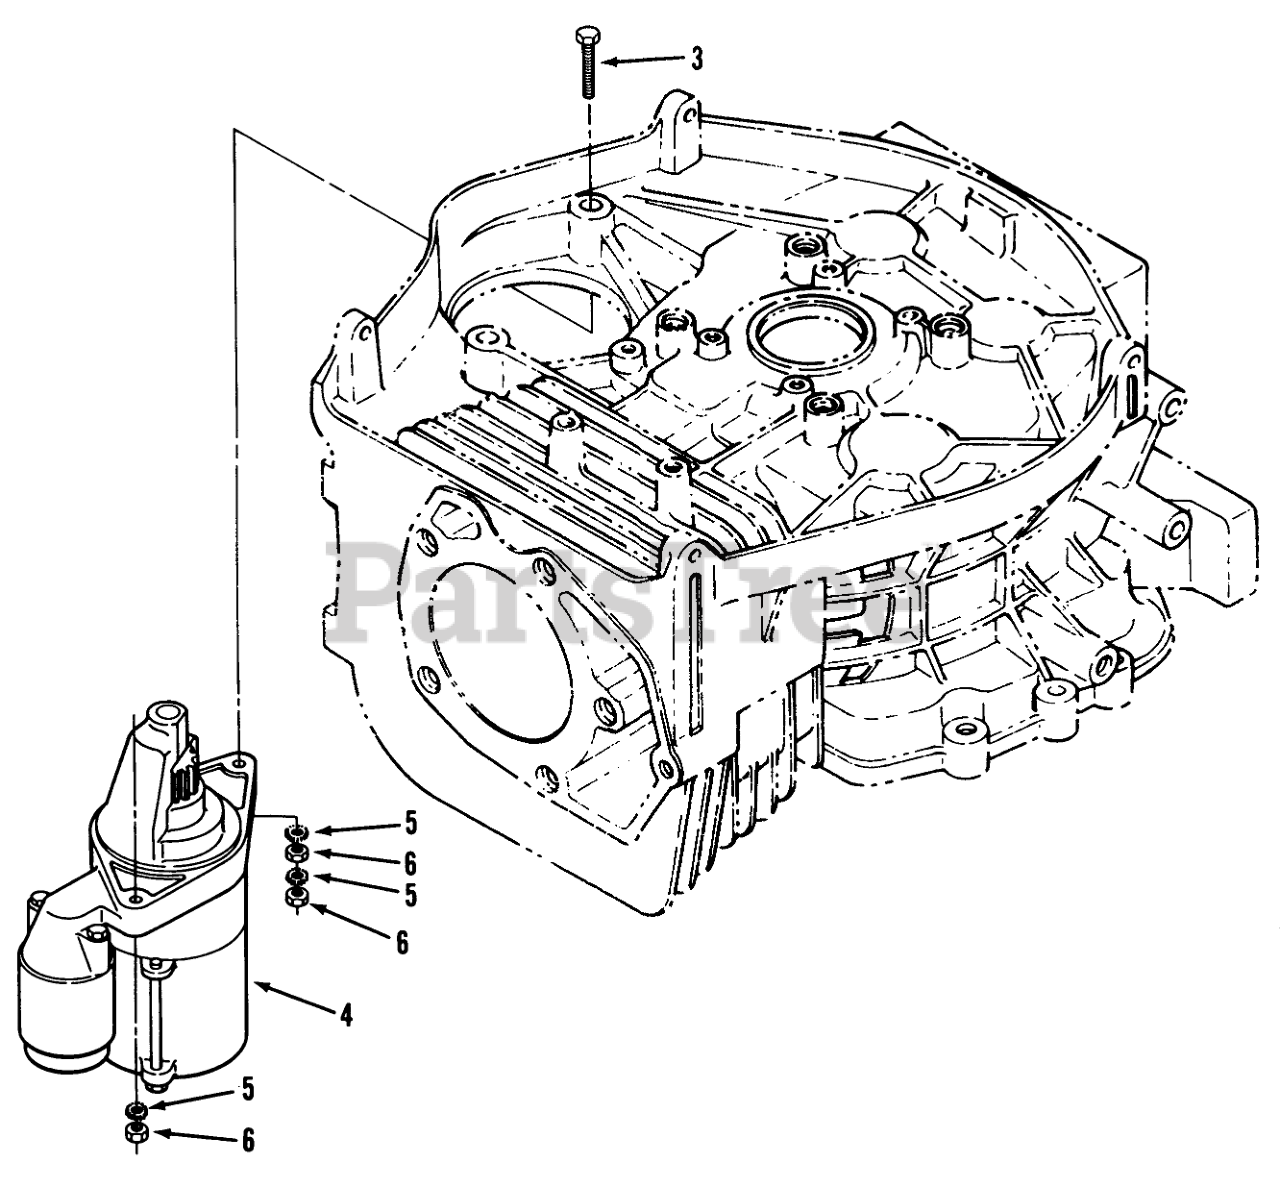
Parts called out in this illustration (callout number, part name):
3	Screw
4	STARTER
5	WASHER
6	Nut
